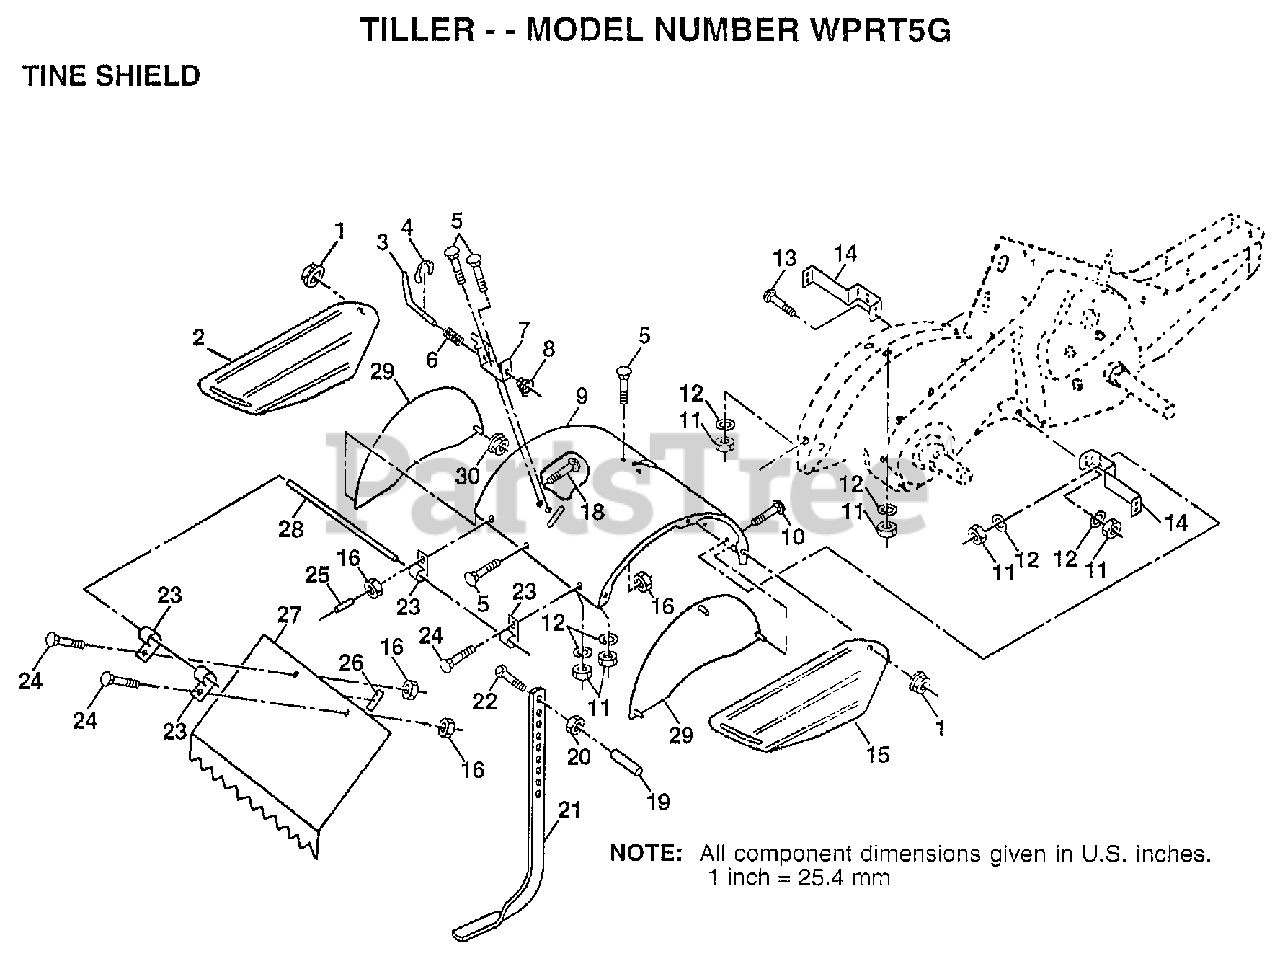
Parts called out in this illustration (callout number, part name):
1	NUT
2	"SHIELD,SIDE,O.LH"
3	STAKE PIN TI
4	KLIP RING TI
5	BOLT
6	SPRING TI
7	LATCH BRACKET TI
8	SPRING CRT
9	TINE SHIELD
10	BOLT
11	NUT.HEX.5/16-18
12	LOCKWASHER
13	BOLT
14	"BRACKET,SHIELD"
15	SHIELD SIDE O.RH
16	NUT
18	BOLT
19	GRIP CRT
20	NUT.HEX.3/8-16UNC
22	BOLT
23	HINGE CRT
24	BOLT
25	VINYL CAP TI
26	PAD IDLER TI
27	LEVELING SHIELD
28	PIN HINGE
29	SIDE SHIELD
30	LOCKNUT TI
